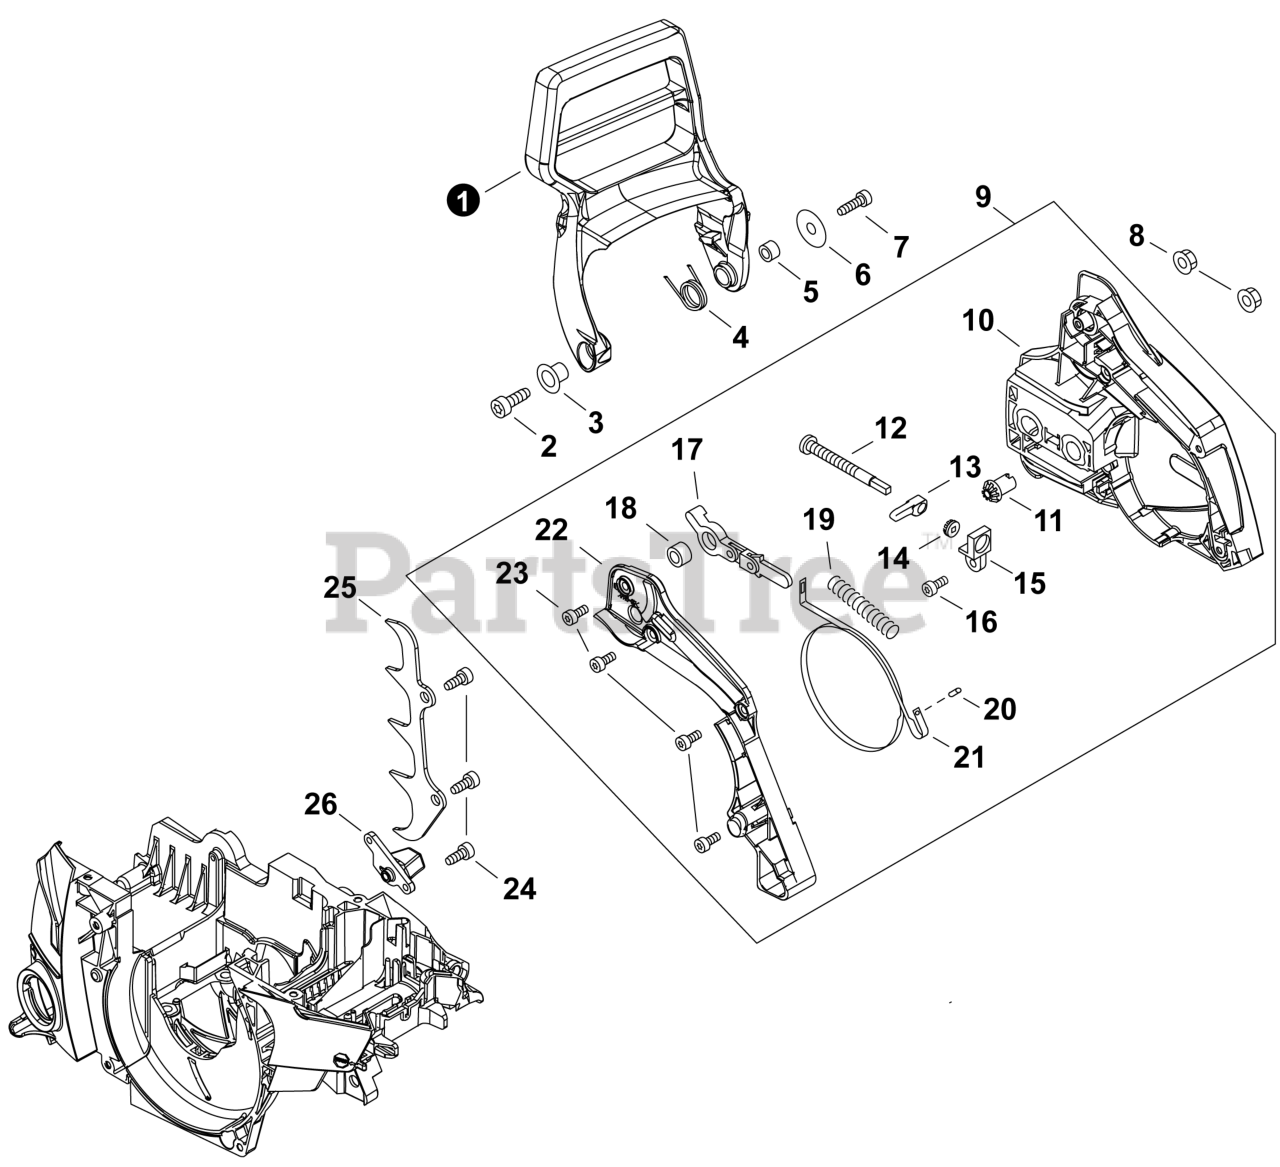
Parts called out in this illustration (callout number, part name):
1	LEVER, BRAKE
2	BOLT, TORX 5x20
3	COLLAR 10
4	SPRING, TORSION
5	SPACER 8x12x9
6	WASHER 4.2x16.5x1
7	BOLT, TORX 4x16
8	NUT, FLANGE M8x1.25
9	BRAKE ASSY, CHAIN
10	GUARD, SPROCKET
11	GEAR, BEVEL
12	SCREW, CHAIN TENSION
13	TENSIONER, CHAIN
14	GEAR, BEVEL
15	COLLAR 8
16	BOLT, TORX 4x16
17	CONNECTOR, BRAKE
18	SPACER 8x12x9
19	SPRING, COMPRESSION
20	PIN 3x12
21	BAND, BRAKE
22	COVER, BRAKE
23	BOLT, TORX 4x16
24	BOLT, TORX 5x20
25	SPIKE, BUMPER
26	CATCHER, CHAIN
